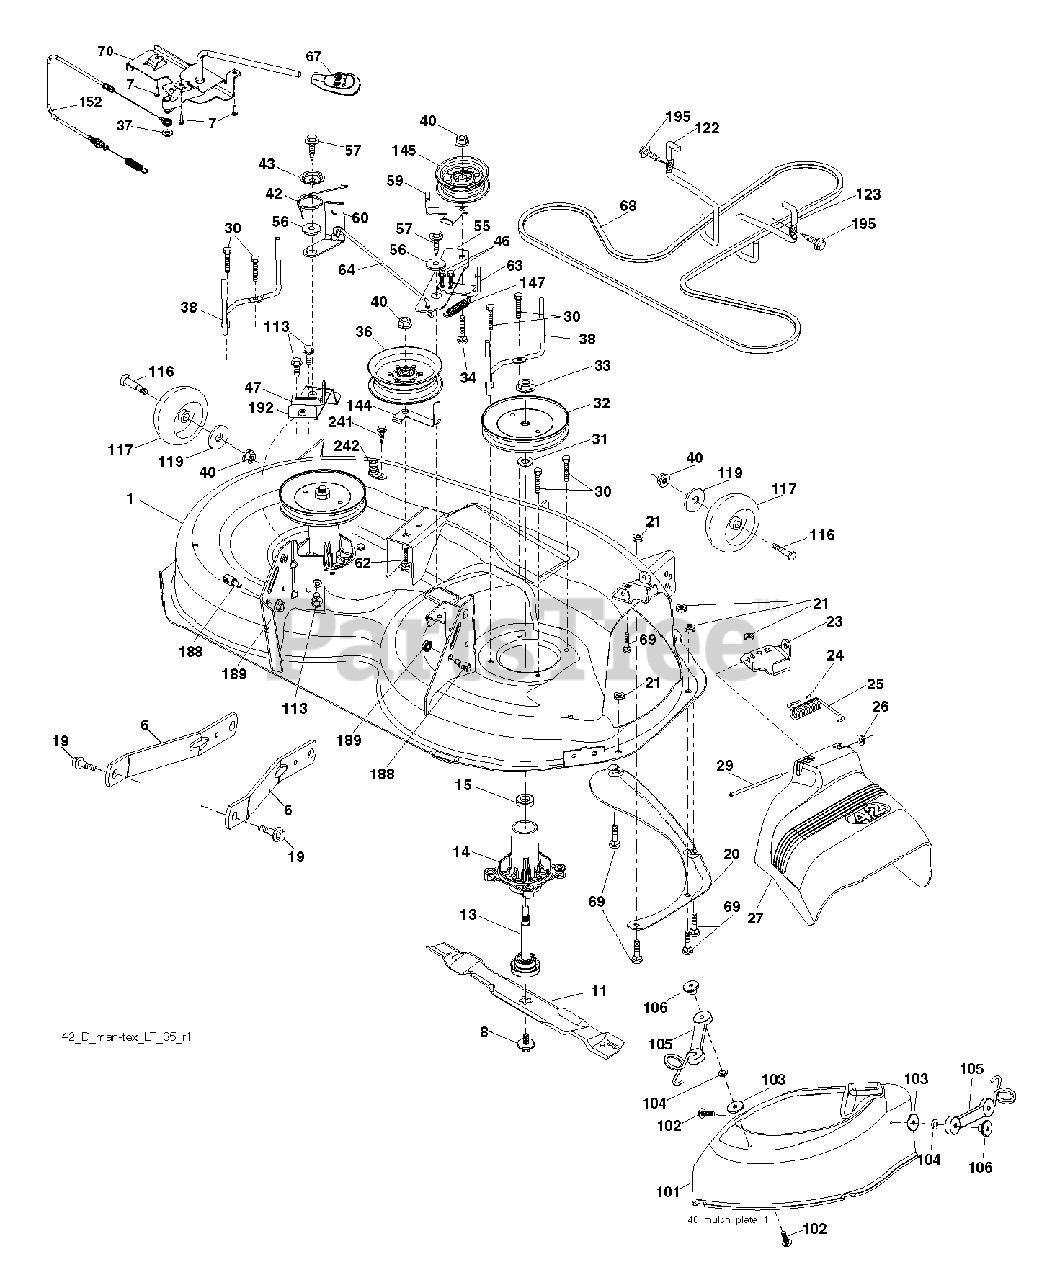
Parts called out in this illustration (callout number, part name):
1	DECK SVC 42" 2GWB 419175X668
6	ARM.SUSPENSION.MOWER.R
7	SCREW.#10 X 0.750.BOS
8	BOLT.WASHER.ASM.7/16-2
11	42" HI-LIFT BLADE
13	SHAFT.ASM.MDRL.N/GREASE.38
14	HOUSING.MANDREL.4PT.
19	BOLT.SHOULDER
20	BAFFLE.VORTEX
21	LOCKNUT
23	BRKT.DEFLECTOR.38"2005+
24	CAP-SLEEVE LT
25	SPRING.TORSION.DEFLECT
26	NUT PUSH M
27	SHIELD.DEFLECTOR.MOWER.42"BLAC
29	ROD.HINGE
30	SCREW, WASHER HEAD
31	WASHER.SPACER.MANDREL
32	PULLEY.MANDREL.5.438.PD
33	NUT.FLANGE.LOCK.TOP
34	BOLT.3/8-16X1.50
36	PULLEY.IDLER.2006
37	WASHER
38	KEEPER.BELT.MANDREL.PULLEY
40	NUT LOCK FLG 3/8-16 UNC
42	SPRING.TORSION.BRAKE
43	SRPING.TORSION.RETAINE
46	SCREW.1/4-20X5/8
47	BRKT.CLUTCH.CABLE
55	IDLER.ARM.42"
56	SPACER.RETAINER
57	SCREW 3/8-16X1
59	GUARD, BELT
60	ARM BRAKE MOWER
63	ARM BRAKE MOWER
64	LINKAGE.BRAKE.ASM.ZINC
67	HANDLE.CLUTCH.CABLE.LT
68	BELT.DECK.DRIVE.42"
69	BOLT
70	CLUTCH.ASM.MANUAL.YT.PREDATORQ
102	SCREW
104	LOCKWASHER (3 2)
105	LATCH ASSY
106	WELDNUT
113	BOLT.5/16HEX.WHS.HD
116	BOLT.SHOULDER.3/8-16X3-5/8.
117	WHEEL. GUAGE RALLY
119	WASHER
122	KEEPER BELT ENGINE LH
123	KEEPER BELT RH
144	KEEPER.BELT.MOWER
145	PULLEY.IDLER.48"PRIMARY
147	RETURN SPRING
152	CABLE.CLUTCH.CABLE.W/SPRING
188	STUD.FASTNER.W/ANTI-ROTATE
189	NUT LOCK HEX FLANGE 5/16-18
192	BRKT.BRAKE.STAND.LH.
195	SCREW, 3/8-16X3/4
241	SCREW.TT.#10-32X.5.3/8.FLANGE
242	PORT.WASHOUT
